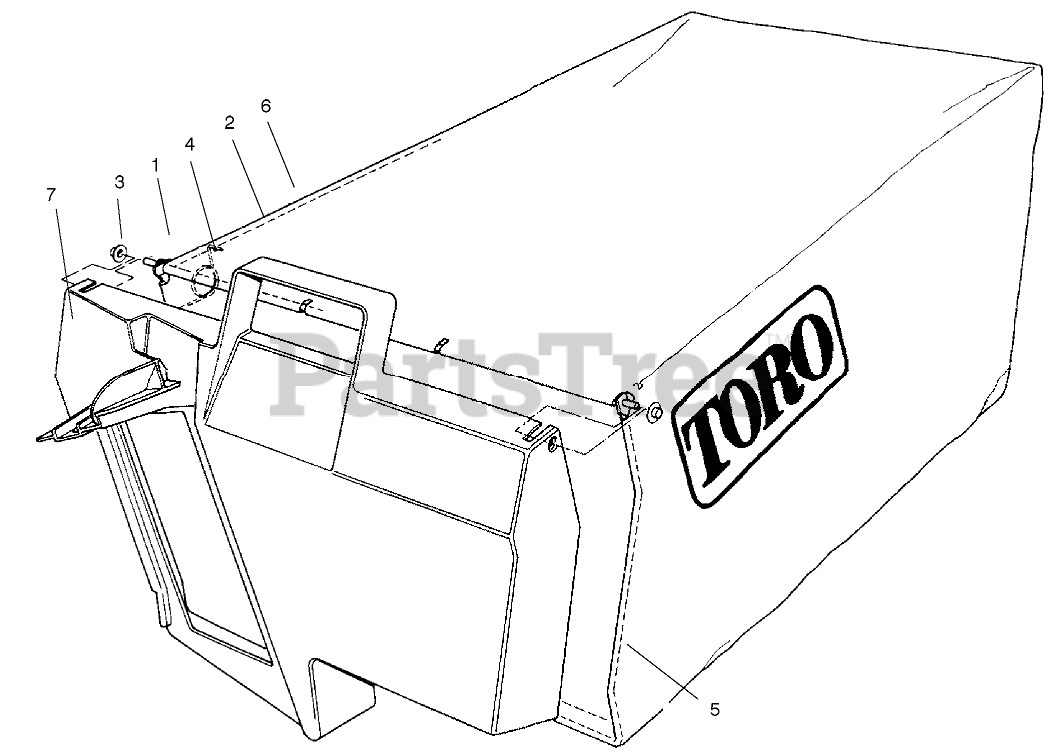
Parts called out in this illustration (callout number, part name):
1	Grass Bag ASM
1	HINGE-DOOR, BAG
2	FRAME-BAG, UPPER
3	NUT-PUSH
4	SPRING
5	FRAME-BAG
6	BAG-GRASS
7	DOOR-BAG, GRASS
